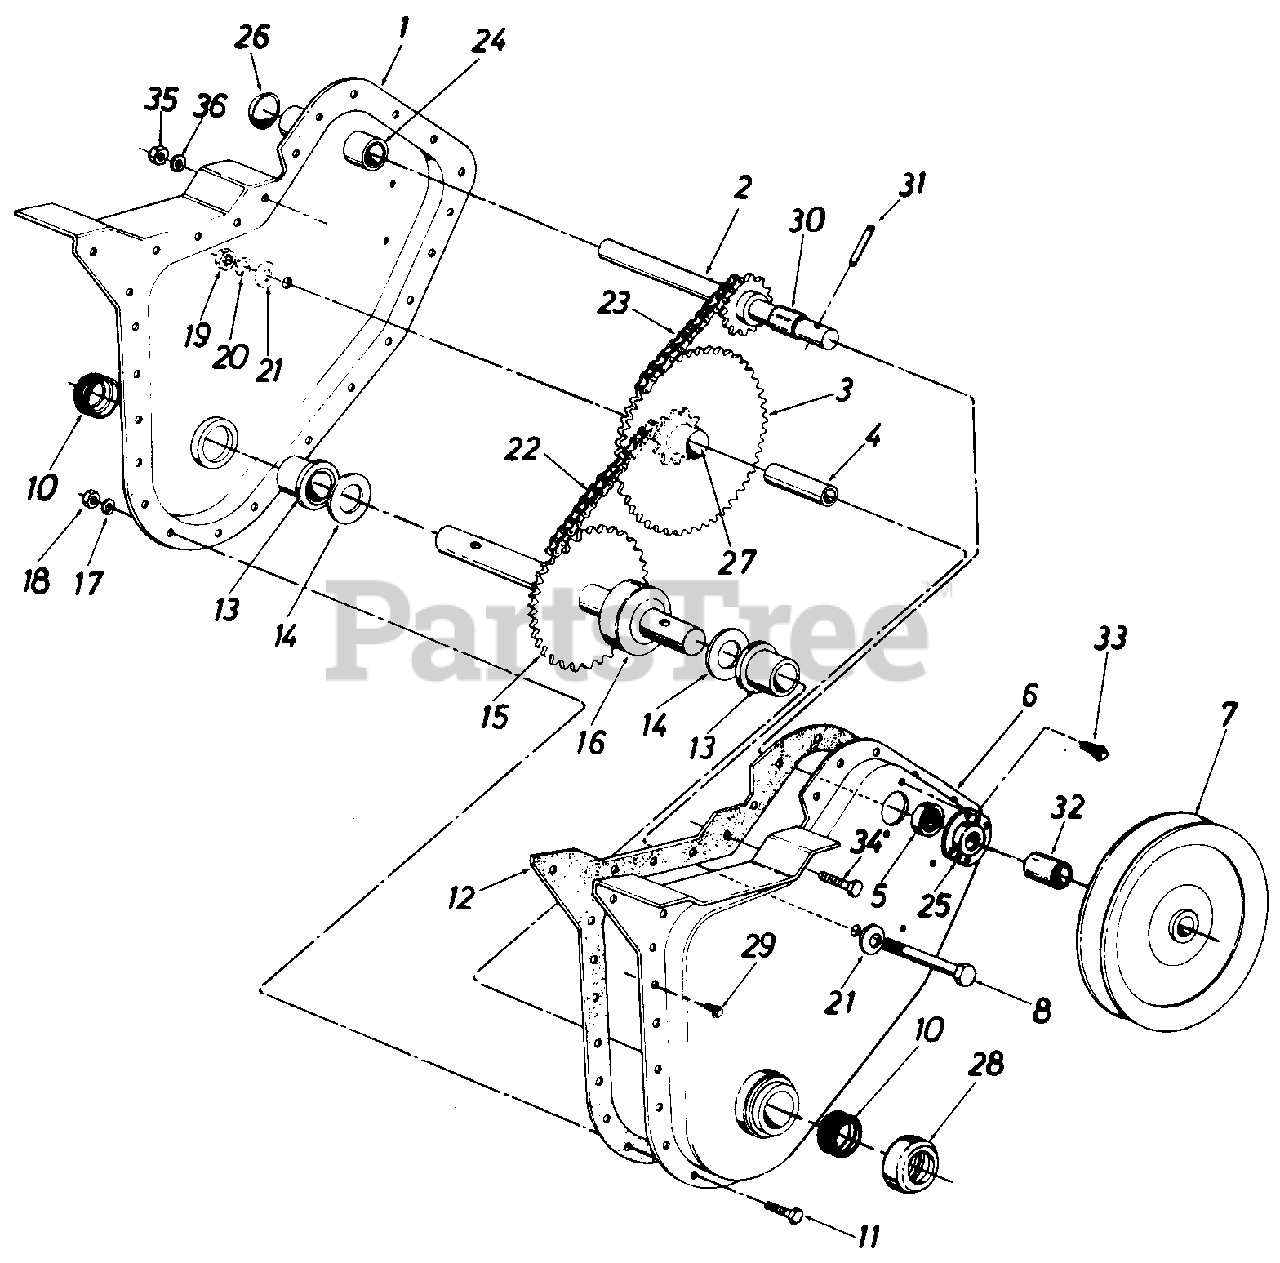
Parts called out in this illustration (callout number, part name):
1	483 Chain Case Ass'y.-R.H.
2	Input ShaR Ass'y.
3	Hub and Sprocket Ass'y.
4	Bearing Inner Race
5	Ball Bearing
6	483 Chain Case Ass'y.-L.H .
7	Pulley-Chain Case
8	Hex Bolt 3/8-24 x 2.5" Lg.
10	Seal
11	Hex Bolt 1/4-28 x .625" Lg.
12	Gasket
13	Flange Brg. .879" l.D.
14	Fl-Wash. .88" l.D. x 1.5"
15	Tine ShaR Ass'y.
16	Spacer 7/8" l.D. x 2" O.D. x 68" Lg.
17	L-Wash. 1/4" l.D.
18	Hex Nut l/4-28 Thd.
19	Hex Ins. L-Nut 3/8-24 Thd.
20	L-Wash. 3/8" I.D.
21	Bell-Wash..406" I.D.
22	Chain #420l/2" Pitch x 37 Links
22	#420 Master Link
23	Chain #35 .375" Pitch x 49 Links
23	#35 Master Link
24	Bearing .62" l.D. x .813"
25	Bearing Housing
26	Expansion Plug 13/16" Dia.
27	Bearing
28	Dust Cap
29	Hex Wash. Hd. Self-Tap Scr. 1/4-20 x .50" Lg.
30	Spacer .63" I.D. x .77" O.D. x .38" Lg.
31	Spring Pin Spiral 1/4" Dia. x 1l/2" Lg.
32	Spacer .647 X 1.25
33	Hex Wash. Hd. Self-Tap Scr. l/4-20 x .38" Lg.
34	Hex Bolt 5/16-18 x .75" Lg.
35	Hex Nut 5/16-18 Thd.
36	L-Wash. 5/16" I.D.
